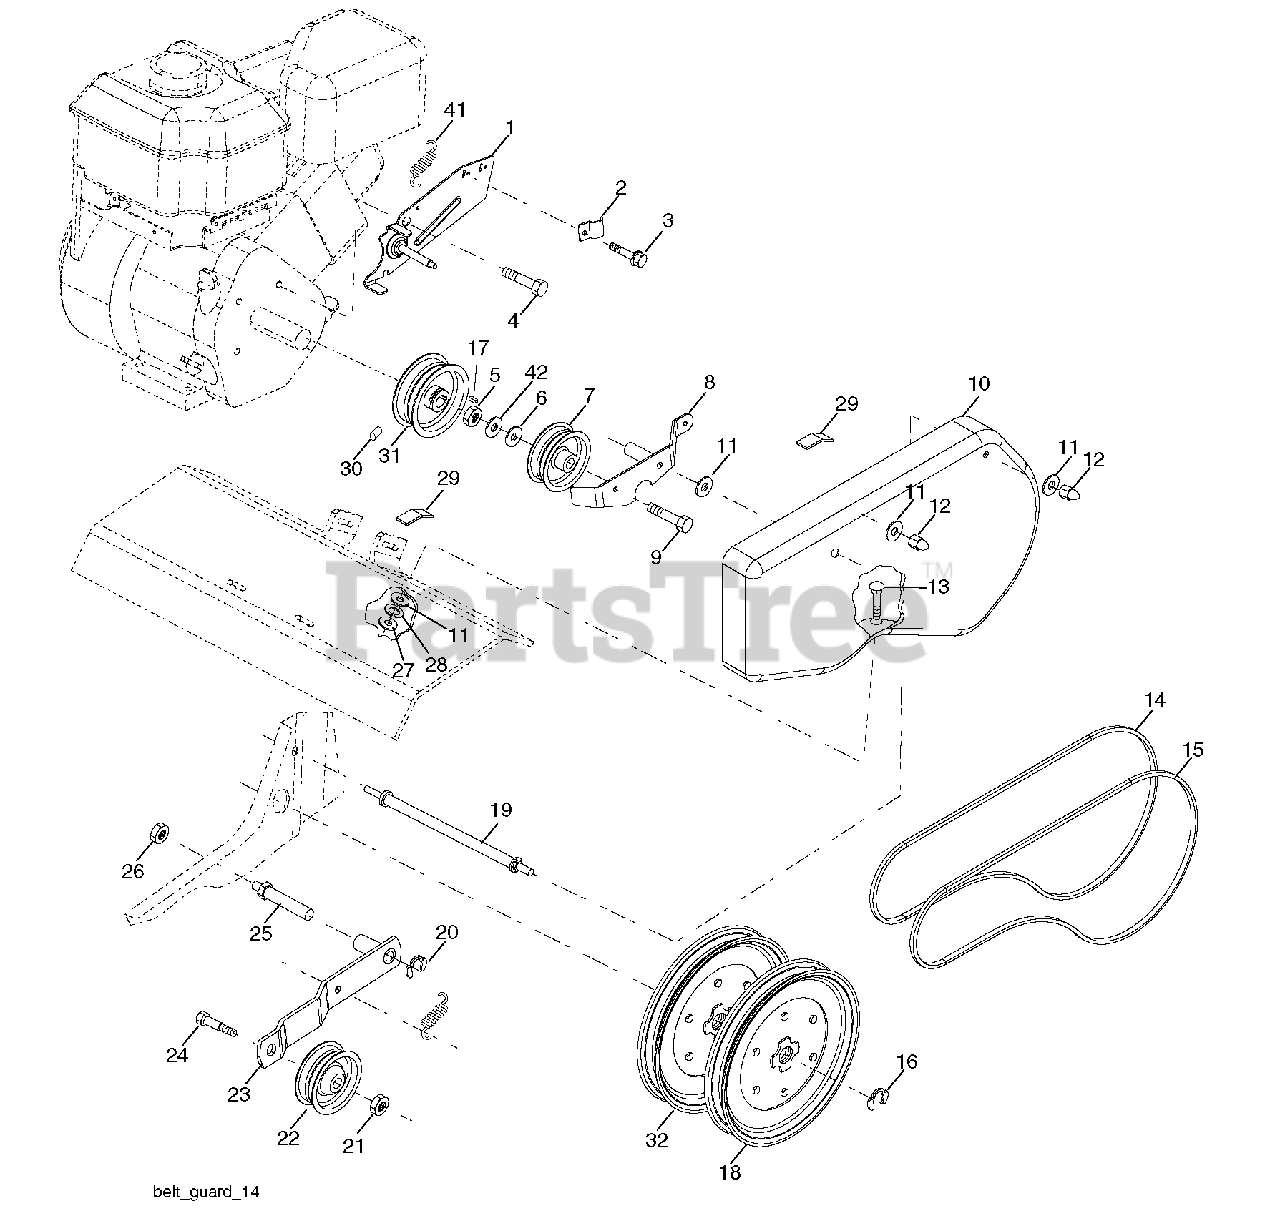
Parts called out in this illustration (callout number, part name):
1	Assembly, Bracket, Belt Guard
2	Clip, Cable
3	Screw #10-24 x 1/2
4	Bolt, Hex Head 1/2-20 x 3/4
5	Nut, Hex 3/8-16
6	Washer 13/32 x 13/16 x 16 Ga.
7	Pulley, Idler, Reverse
8	Assembly, Arm, Reverse Idler
9	Bolt, Hex Head 3/8-16 x 1-3/4
10	Guard, Belt
11	Washer 9/32 x 5/8 x 16 Ga.
12	Nut, Cap 1/4- 20
13	Bolt, Carriage 1/4-20 x 3/4
14	V-Belt (Forward Motion)
15	V-Belt (Reverse)
16	Ring, Retainer
17	Key, Square
18	Sheave, Transmission "Flat"
19	Bolt, Belt Guard
20	Ring, Klip
21	Nut, Hex, Jam 3/8-16
22	Pulley, Idler
23	Arm, Idler
24	Bolt 3/8-16 x 1-1/4
25	Shaft, Idler Arm
26	Nut, Hex, Jam 5/16-18
27	Nut, Hex 1/4-20
28	Washer, Lock 1/4
29	Pad, Idler
30	Screw, Set , Socket, Headless C.P. 1/4-20 x 1/4
31	Sheave, Engine
32	Sheave, Transmisison
41	Spring Extension
